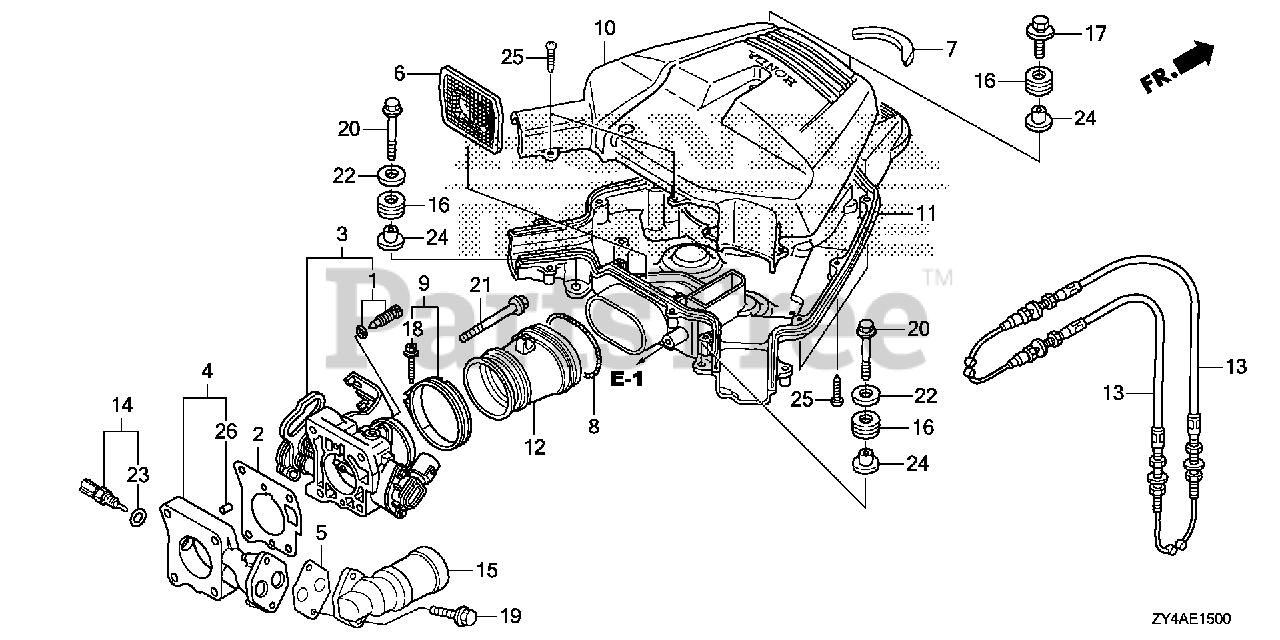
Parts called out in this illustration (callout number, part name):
2	GASKET, THROTTLE BODY
3	BODY ASSY., THROTTLE
4	SPACER, THROTTLE BODY
5	GASKET, EAC VALVE
6	TRAP, FLAME
7	RUBBER, SEAL MUFFLER
8	SPRING, AIR FLOW TUBE
9	BAND, AIR FLOW
10	CASE A, MUFFLER
11	CASE B, MUFFLER
12	GROMMET, MUFFLER
13	CABLE, THROTTLE
14	SENSOR ASSY., AIR TEMPERATURE
15	VALVE ASSY., EAC
16	GROMMET, CASE (LOWER)
17	BOLT-WASHER (6X25)
18	BOLT-WASHER (5X30)
19	BOLT, FLANGE (6X22)
20	BOLT, FLANGE (6X60)
21	BOLT, FLANGE (8X65)
22	WASHER, PLAIN (6MM)
24	COLLAR, MODULE IGNITION CONTROL CASE (CDI)
25	SCREW, TAPPING (5X20)
26	PIN, DOWEL (6X10)
